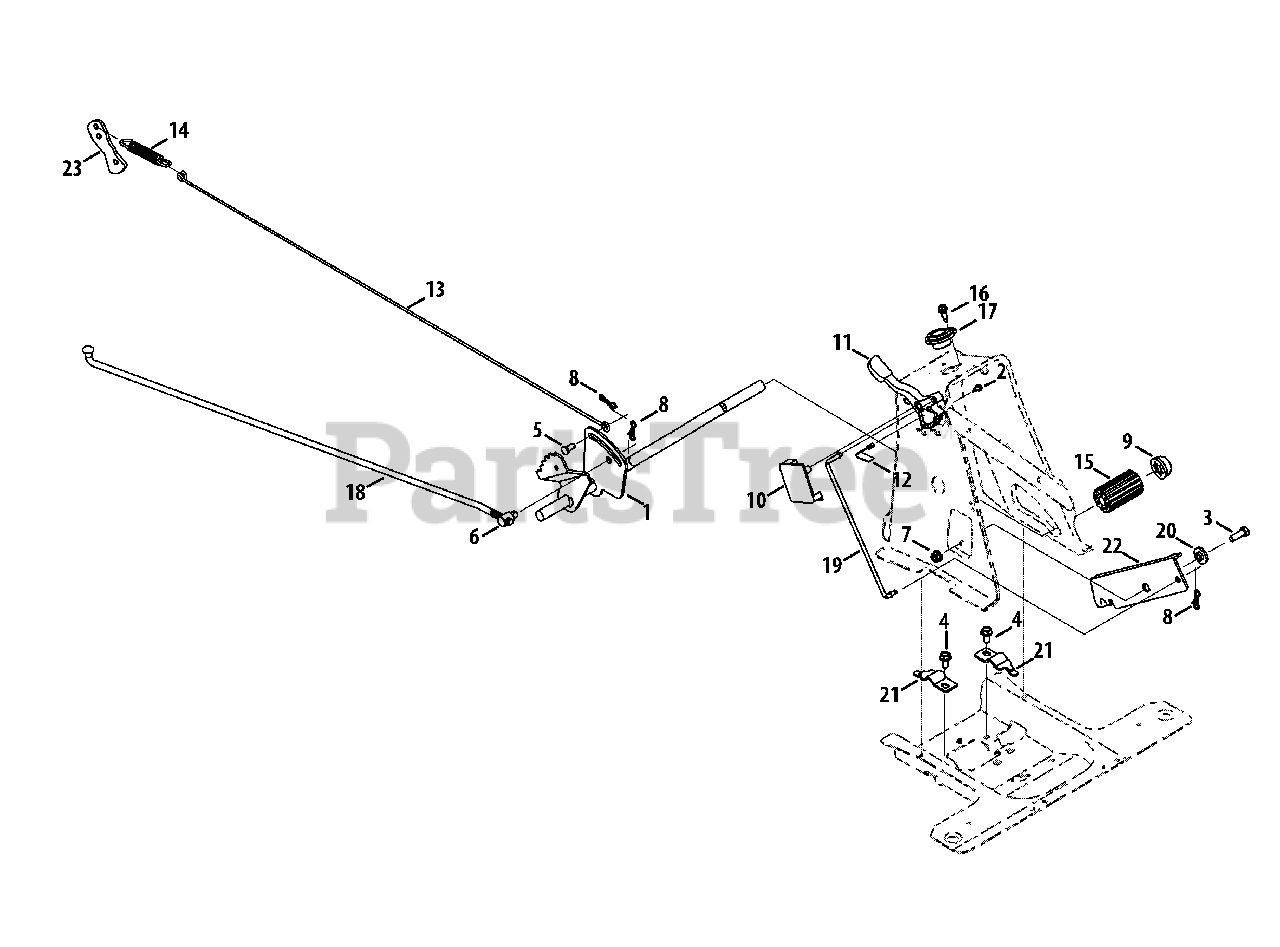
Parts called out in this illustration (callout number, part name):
1	Brake Pedal Assembly
2	Screw, #10-16:0.500
3	Hex Head Scerw, 5/16-18:1.00
4	Tap Screw, 5/16-18:.750
5	Clevis Pin, 5/16 x 5/8
6	Ferrule 3/8-24 X .375 Dia.
7	Flange Lock Nut, 5/16-18
8	Bow-Tie Cotter Pin, 72
9	Push Cap, 5/8
10	Speed Control Cover
11	Speed Lever, 6-SPEED
12	Shift Spring
13	Brake Rod, 39.92 LG
14	Extension Spring, .59 OD x 4.00 LG
15	Foot Pad, 2.5" LG.
16	Shoulder Screw, .368 X.113, 1/4-20
17	Steering Col. Bearing, .880 ID X 1.36
18	Variable Speed Control Rod
19	Speed Selector Control Rod
20	Shoulder Spacer
21	Pedal Strap Support Bracket, 5/8
22	Speed Latch Bracket
23	Brake lever Bracket
